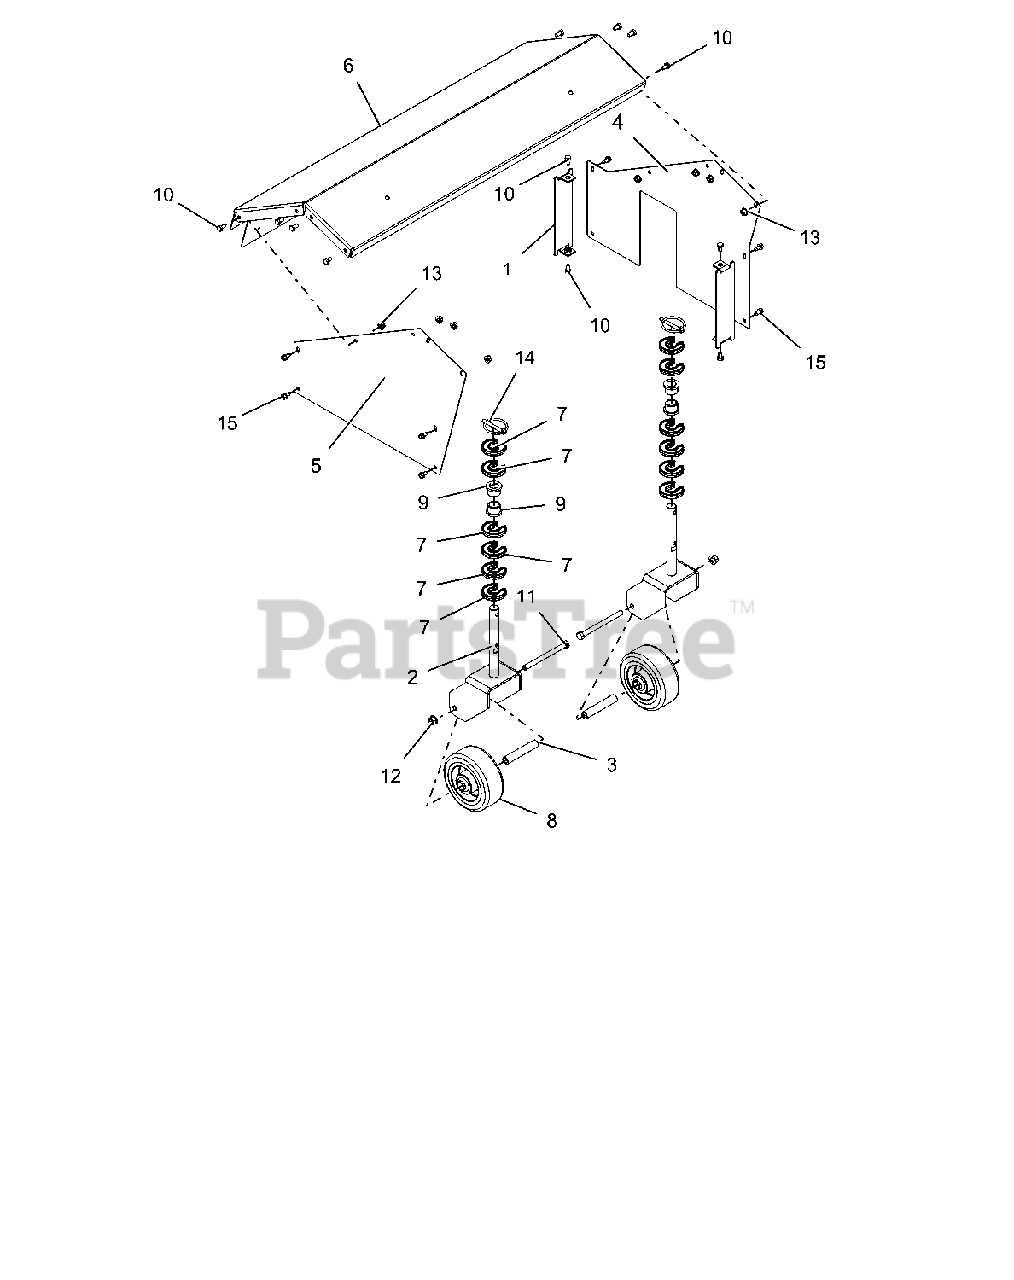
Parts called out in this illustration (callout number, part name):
1	COVER,END
2	FORK, CASTER-BRUSH
3	SPACER, CASTER WHEEL
4	COVER,LH SIDE BRUSH
5	COVER,RH SIDE BRUSH
6	COVER, 28" BROOM
7	CLIP-HOC FIXED
8	WHEEL, CASTER - 5"OD
9	BUSHING, FLANGE .75X.75X1.0
10	@BLT-HEX .25-20X.50 GR5 YWZC
11	@BLT-HEX .38-16X4.50 GR5 YWZC
12	@NUT-LK-TOP-FLG .38-16 YWZC
13	@NUT-LK-TOP-FLG .25-20 YWZC
14	PIN, LYNCH - .25 X 1.25
15	SCR-TAP .25-20X.50 HWH TR YWZ
